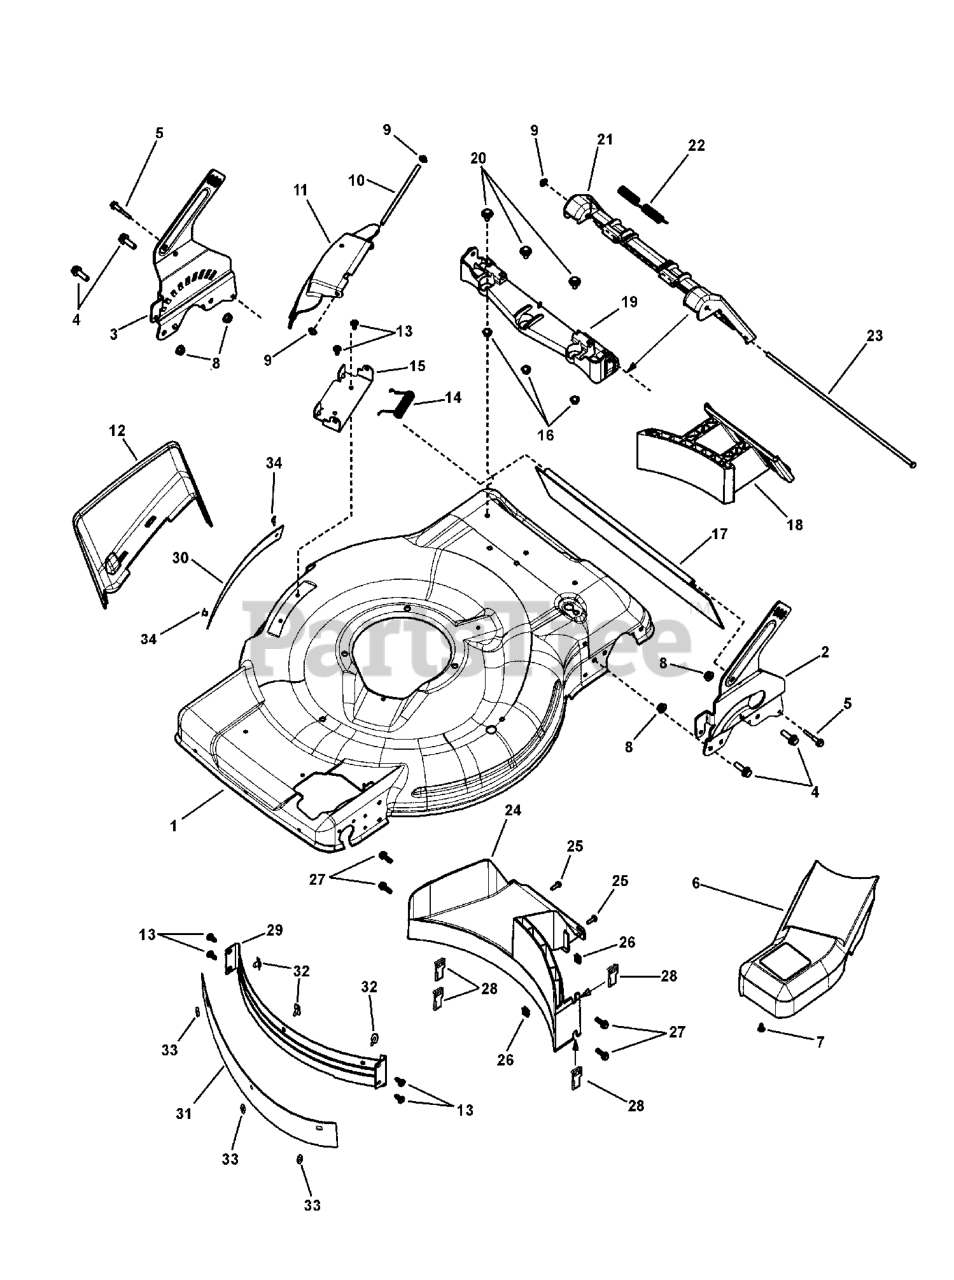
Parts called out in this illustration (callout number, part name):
1	DECK, 22"
2	BRKT, REAR WHEEL, LH, QUICK ADJUST
3	BRKT, REAR WHEEL, RH, QUICK ADJUST
4	HFLB, 5/16-18 X 1 YZ
5	BOLT, DRAG SHIELD, 1/4 - 20 X 1.5
6	COVER, BELT DRIVE, FRONT
7	SCREW, ROUND WASHER HEAD TORX, HI-LO
8	FLN, 5/16-18 YZ
9	PUSHNUT, 1/4
10	ROD, PIVOT
11	COVER, MULCHING
12	CHUTE, SIDE DISCHARGE, WBM, 22"
13	TORX ST, 1/4-20 X .550
14	SPRING, TORSION, CHUTE
15	BRACKET, CHUTE
16	HFLN, 1/4-20
17	GUARD, REAR 22"
18	PLUG, MULCHING, 22" DECK
19	REAR DISCHARGE DOOR HINGE
20	HHSTS, 1/4-20 x 5/8"
21	REAR DISCHARGE DOOR
22	SPRING, TORSION, REAR DOOR
23	ROD, PIVOT, REAR DOOR
24	REAR BAFFLE, FRONT WHEEL DRIVE, WBM
25	HWFST, 10C X 5/8
26	NUT, RETAINER SPEED #10C W/EXT
27	HFLB, 1/4-20X3/4
28	NUT, 1/4 TINNERMAN
29	BAFFLE, FRONT
